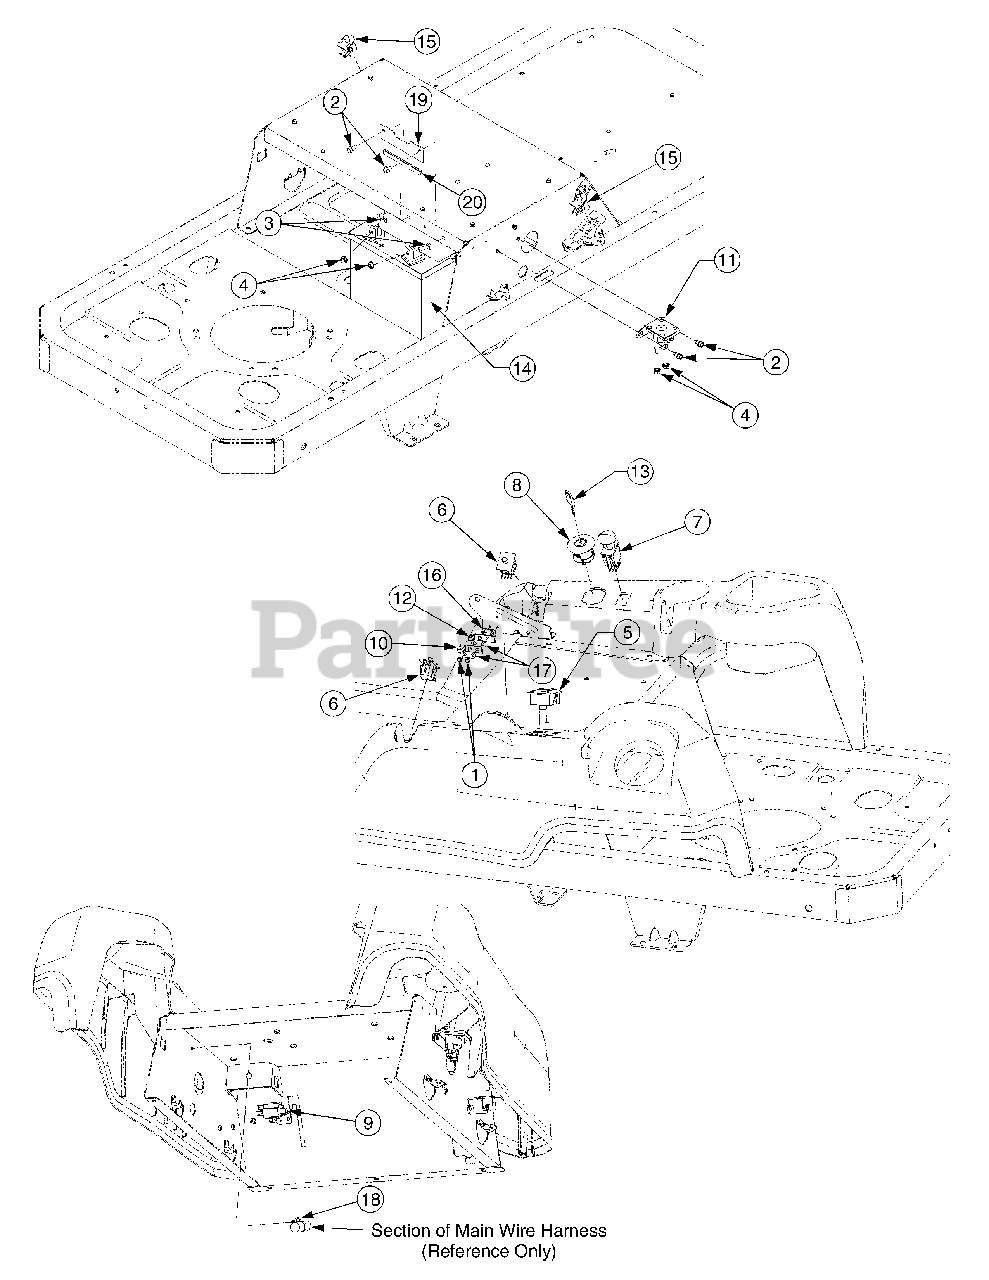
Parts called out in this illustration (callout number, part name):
1	Screw, Hex Wash. Hd. Tapp #8-18 x .5
2	Screw, Hex Wash. Hd. Tapp,1/4-20 x .5
3	Screw, Hex Cap, 1/4-20 x .75 GR5 ...
4	Nut, Hex Sems, 1/4-20
5	Meter, Hour
6	Switch, Dbl. Pole - Neutral
7	Switch, PTO
8	Switch, Ignition
9	Switch, 3-Pole, (NC-NO-NO) - Brake
10	Switch, Outer Seat Spring
11	Solenoid
12	Switch, Inner Seat Spring
13	Key
14	Battery, 235 CCA
15	Switch, Snap Mount (N.C.) - Reverse
16	Plate, Insulator Boss
17	Plate, Insulator
18	Tie, Cable
20	Strip, Trim 4.5 inches
